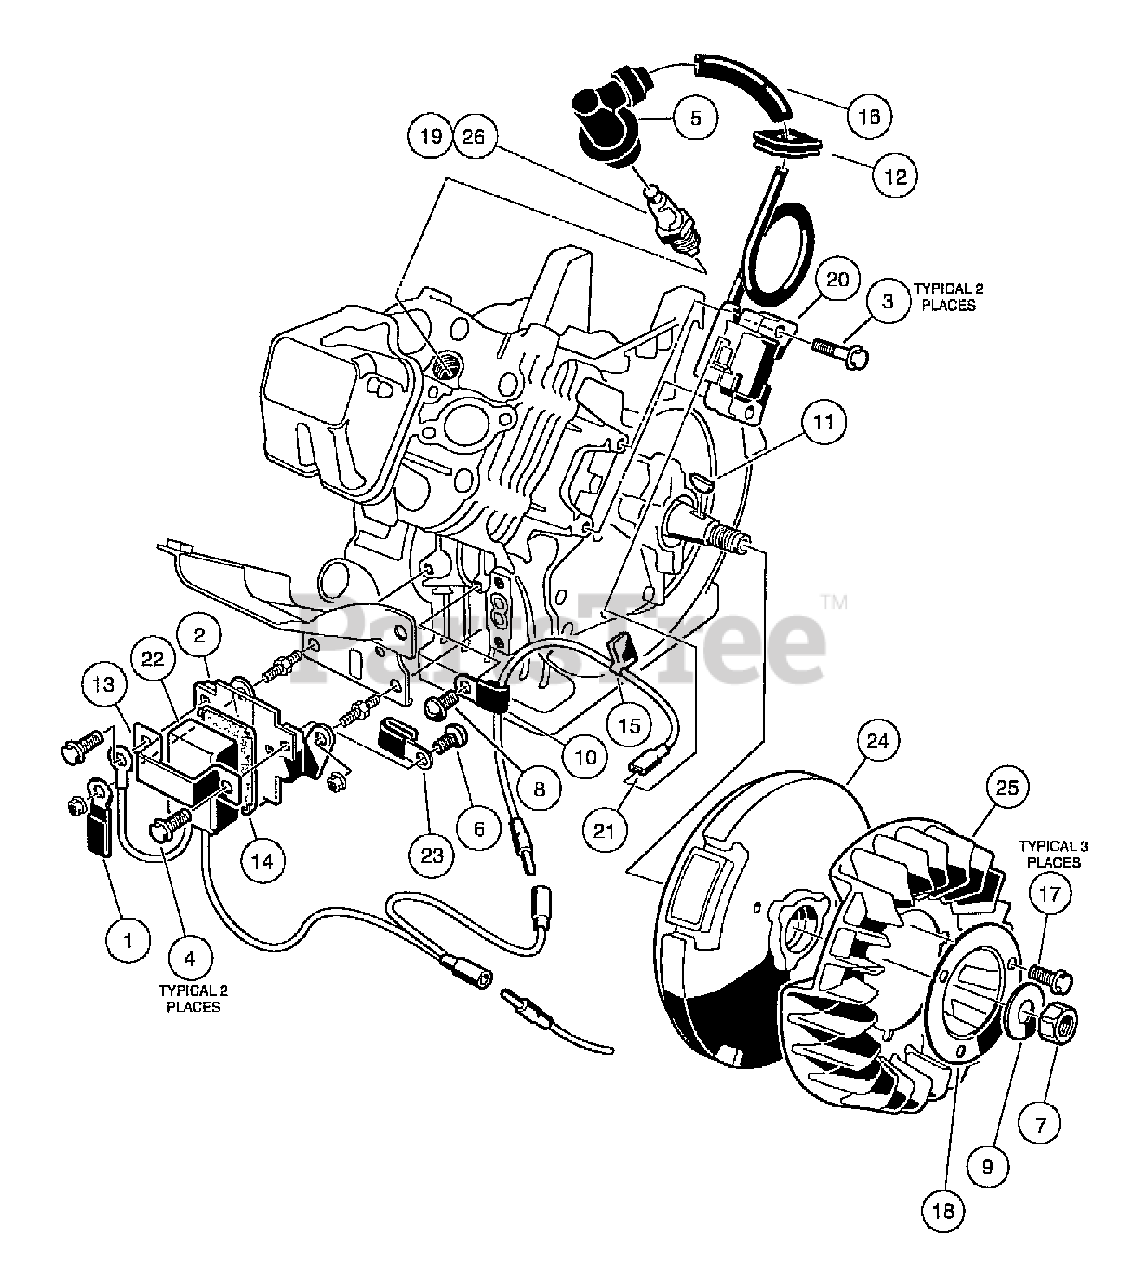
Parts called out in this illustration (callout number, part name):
1	Clamp
2	Bracket, RPM Limiter
3	Bolt. Flange Head
4	Bolt, Flange Head, M6 x 1 x 12 mm
5	Cap, Spark Plug
6	Screw, Pan WP Cross
7	Nut, Hex, Fine
9	Washer, M16 Flat
13	Band, RPM Limiter Mount
14	Damper, RPM Limiter
16	Tube, 7mm X 10mm X 70mm
17	Bolt, Flanged
18	Plate, Flywheel Fan
19	Spark Plug, OHV (Autolite)
20	Coll, Ignition
21	Lead Wire Assy
22	Limiter, RPM
23	Clamp, Steel
24	Flywheel Complete, FE290
25	Fan, FE290 (ow)
26	Spark Plug, OHV (NGK)
